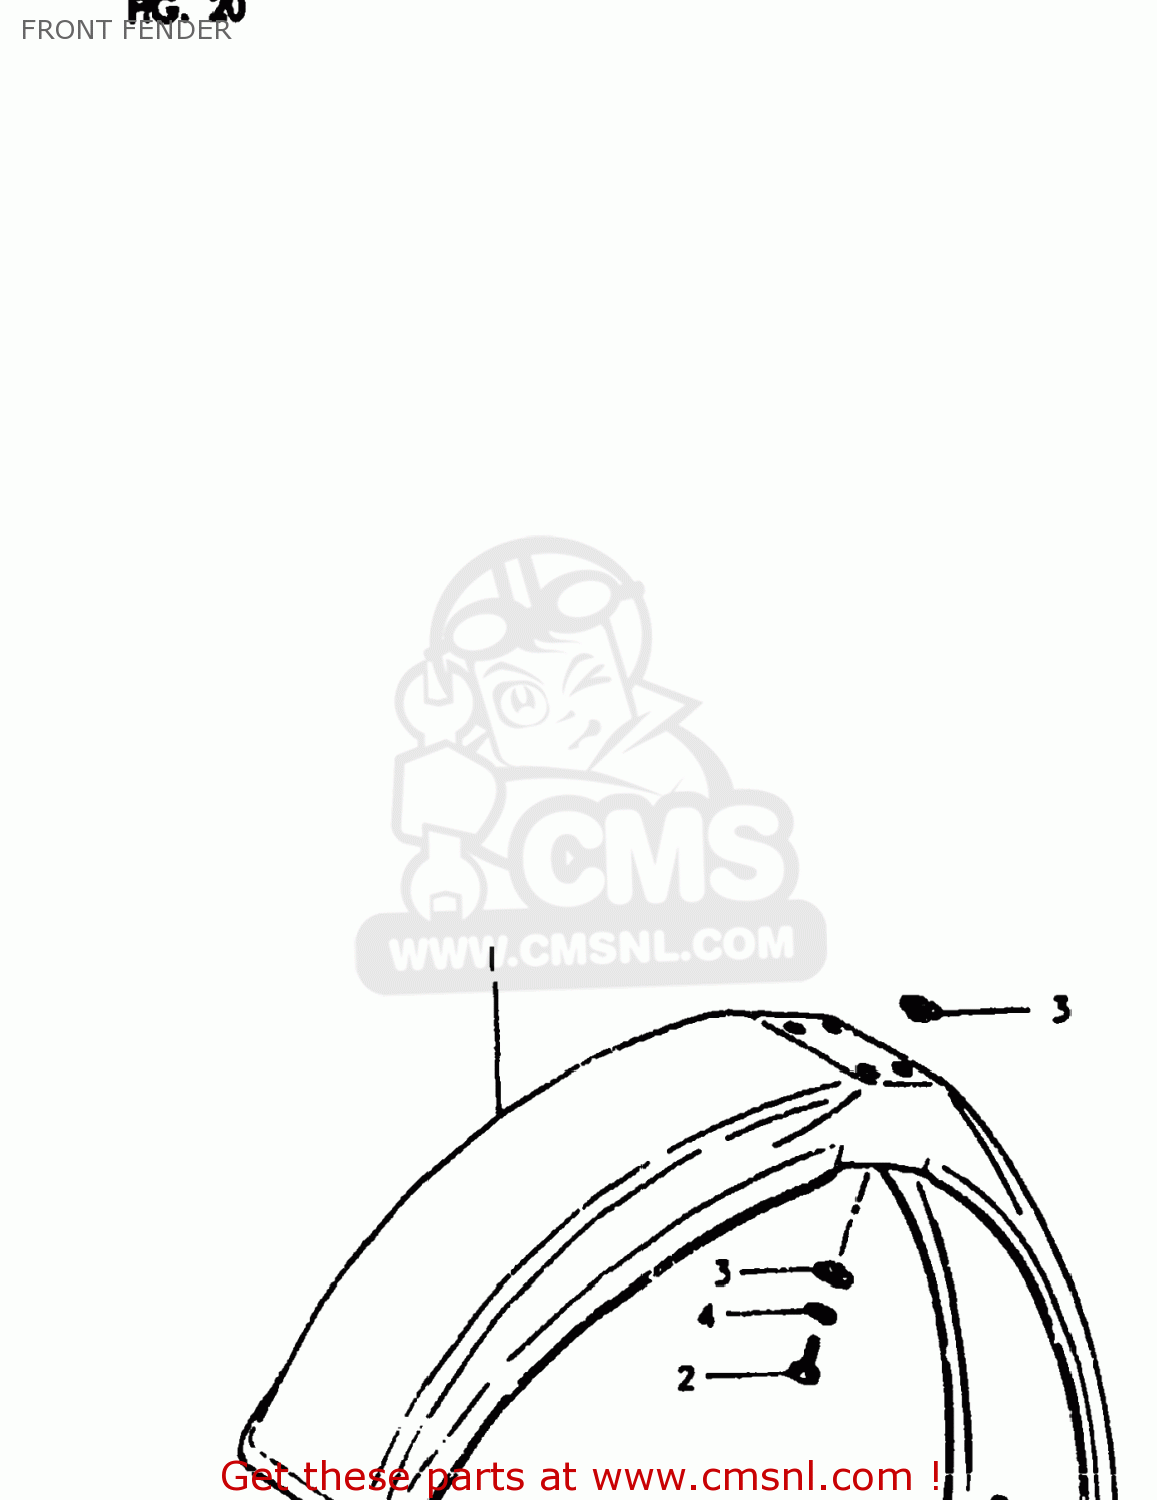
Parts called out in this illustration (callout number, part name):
1	FENDER,FRONT
2	BOLT, UPPER
3	WASHER
4	LOCK WASHER
